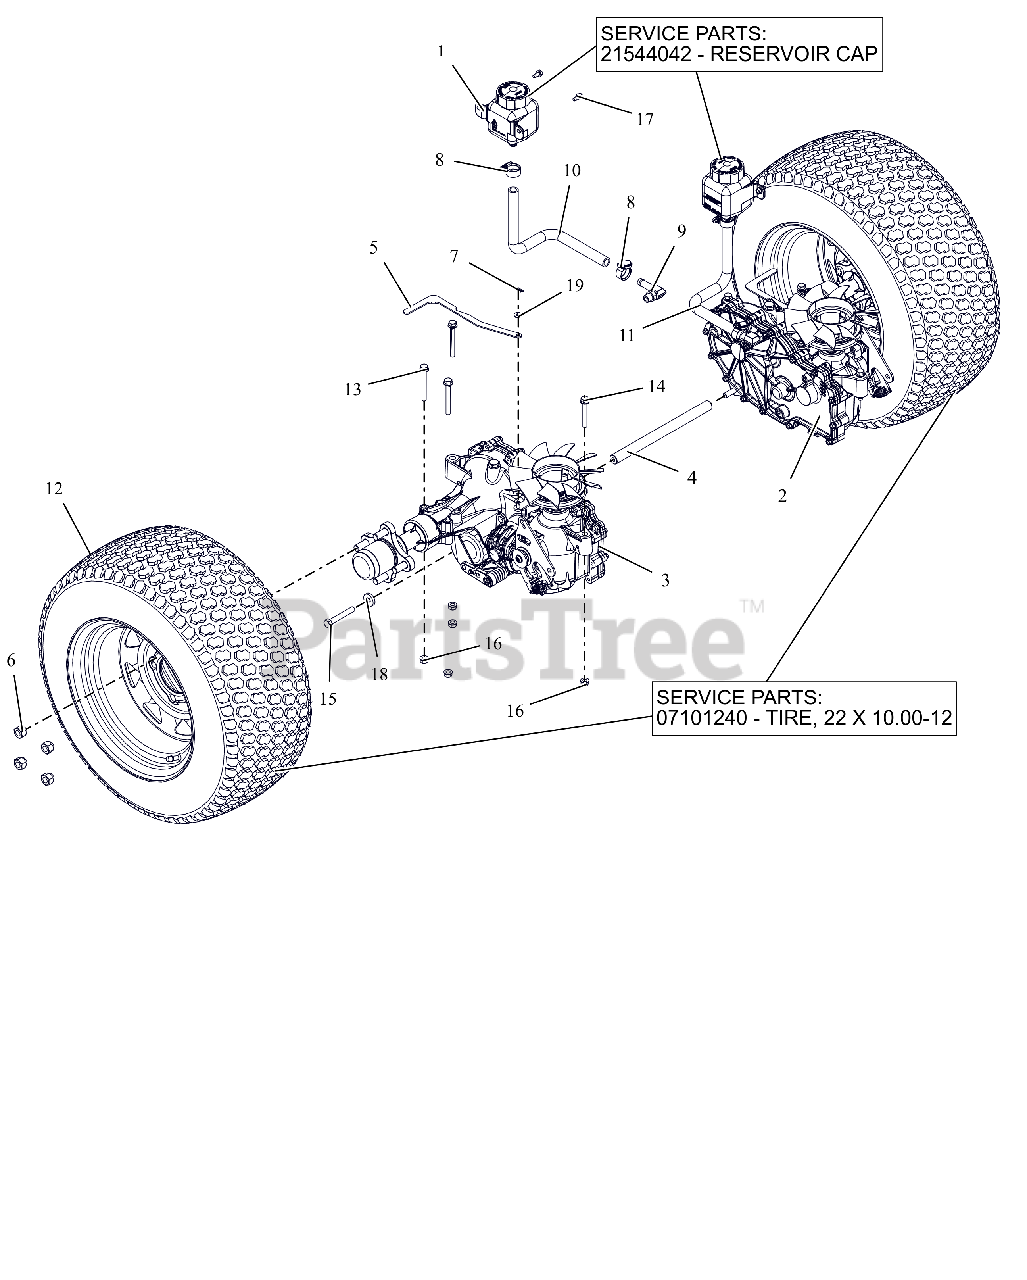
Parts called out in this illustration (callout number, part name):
1	TANK, EXPANSION
1	CAP, HYDRO RESERVOIR REPLAC.
2	TRANSAXLE, ZT3100 LH
3	TRANSAXLE, ZT3100 RH
4	SHAFT, TRANSAXLE SUPPORT
5	BRKT, VALVE DUMP
6	NUT, WHEEL .50-20 ZCC
7	PIN, HAIR #225 .072X1.09
8	CLAMP,.88 DIA. HOSE
9	FITTING, HYD (90 DEG)
10	HOSE, FORMED EXPANSION -HD RH
11	HOSE, FORMED EXPANSION -HD LH
12	ASM, WHL/TIRE 22X10.00-12 K500
12	TIRE, 22X10.00-12
13	BLT,HEX-FLG .31-18X2.75 G5 ZCC
14	BLT,HEX-FLG .31-18X2.25 G5 ZCC
15	BLT, HEX .38-16X2.50 G5 ZCC
16	NUT,LK-CTR-FLG .31-18 GF ZCC
17	SCR-TAP .25-20X.50 HWH ZCC
18	WSHR, FLT .406X1.00X.188 ZCC
19	WSHR,FLT .281X.625X.065 ZCC
